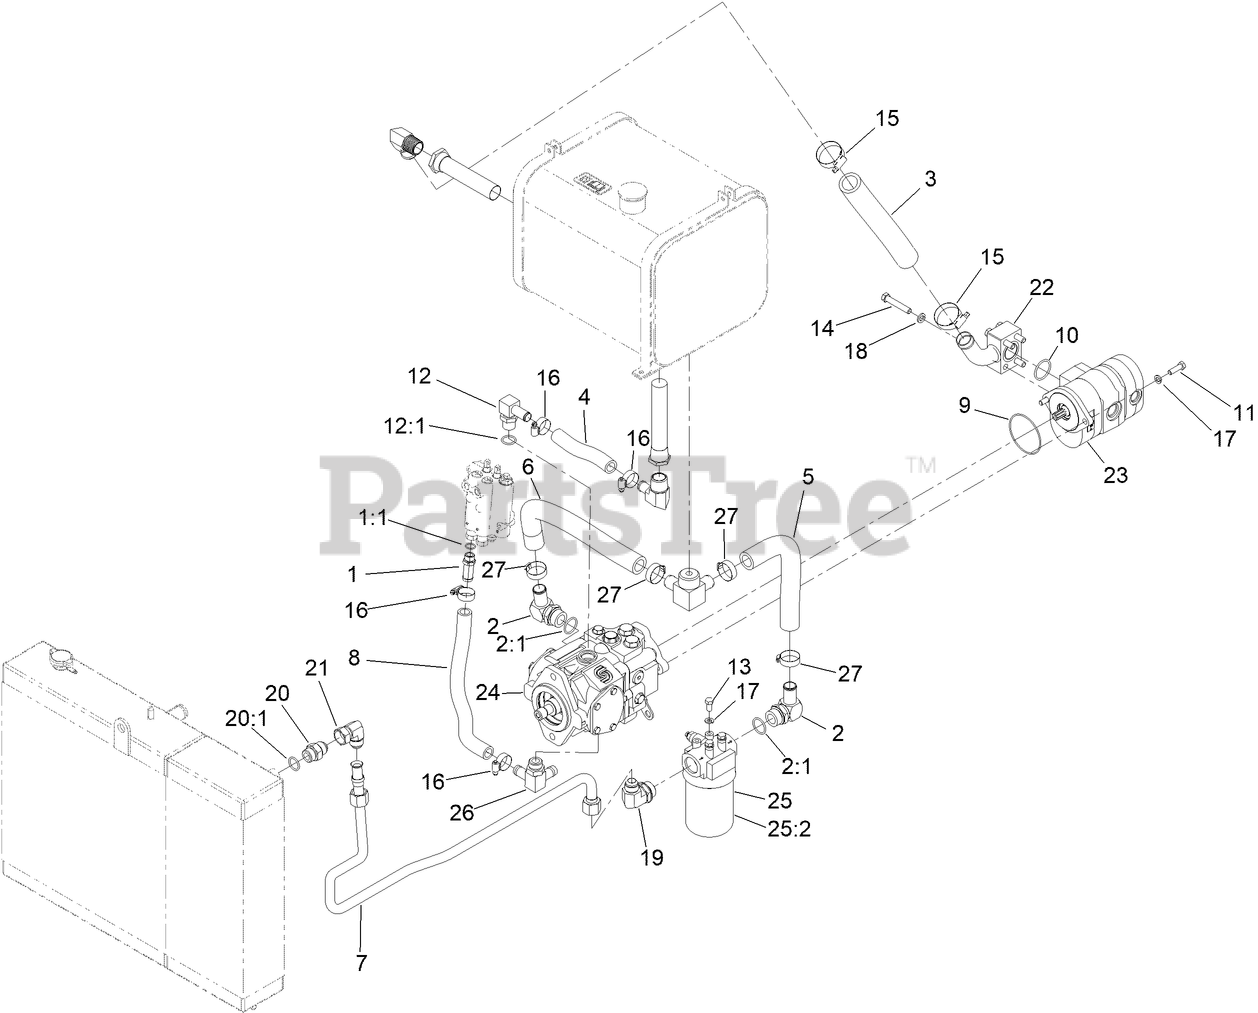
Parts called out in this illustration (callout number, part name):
1	FITTING-STRAIGHT
1:1	O-RING
2	STEM-BARB-90
2:1	O-RING
3	HOSE-SUCTION
4	HOSE-LOW PRESSURE
5	HOSE-HYD, SUCTION
6	HOSE-HYD, SUCTION
7	HYDRAULIC TUBE ASM
8	HOSE-HYD
11	SCREW-HH
12	FITTING-ELBOW, 90
12:1	O-RING
13	SCREW-HH
14	SCREW-HH
15	CLAMP
16	CLAMP-HOSE
17	WASHER-LOCK
18	WASHER-LOCK
20	FITTING-STRAIGHT
20:1	O-RING
21	FITTING-ELBOW, 90
22	FLANGE-PUMP
23	HYD PUMP ASM (DOUBLE)
24	HYD VARIABLE PUMP ASM
25	HYD FILTER ASM
25:2	FILTER-HYD
27	CLAMP-HOSE
